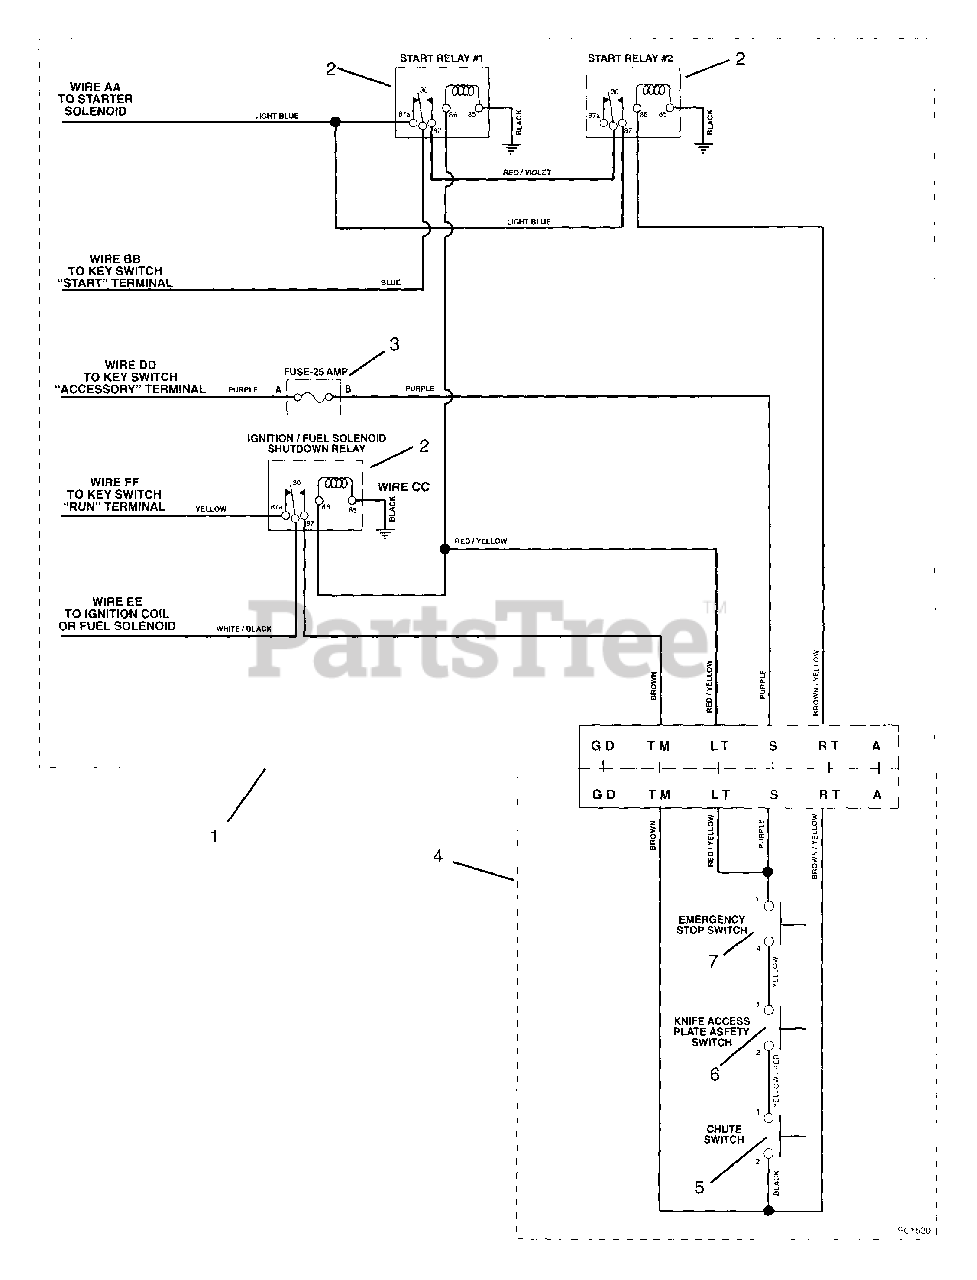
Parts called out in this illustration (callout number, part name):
1	Harness, Tractor Wiring
2	Relay
3	Fuse-25 Amp
4	Harness, Chipper Wiring
5	Switch, Chute Safety
6	Switch, Knife Access Plate Safety Switch
7	Switch, Emergency Stop
